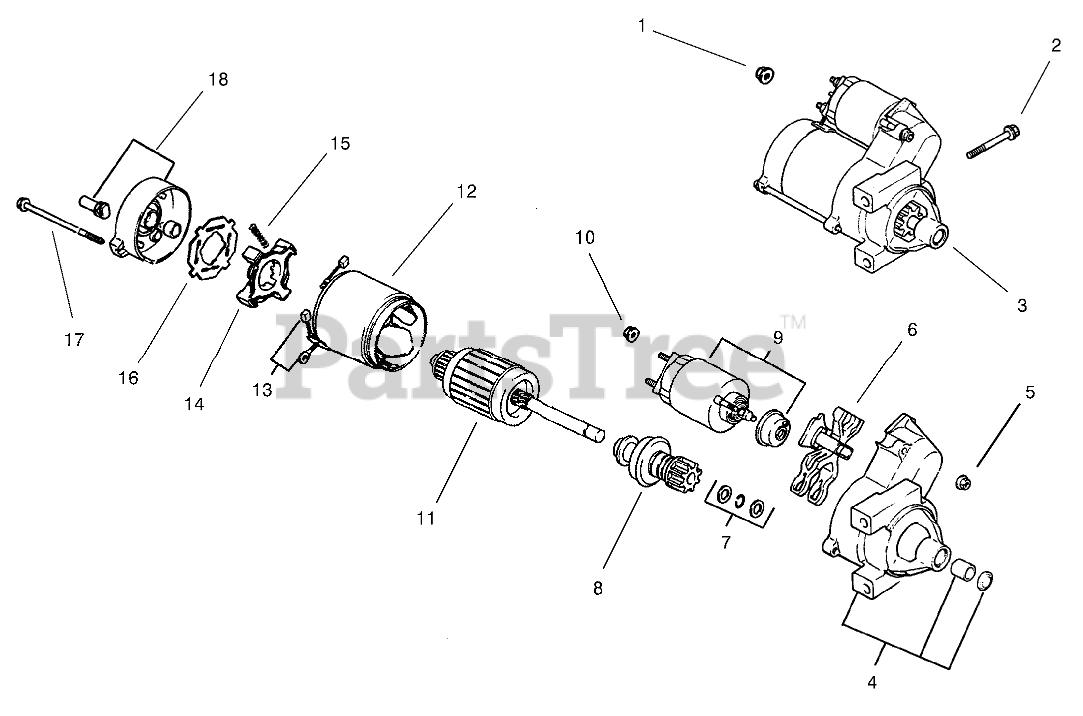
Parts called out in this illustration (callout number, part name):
1	Nut
2	Scew
3	Starter, solenoid shift assembly (Incl. 4-18)
4	Cap-Drive End
5	Nut
6	Lever Starter Drive
7	Washer
8	Drive Pinion
9	Solenoid
10	Nut
11	Armature-Starter
12	Frame
13	Kit, brush & spring (Includes 15)
14	Holder-Brush
15	Spring Brush
16	Insulator
17	Bolt
18	Commutator-End Cap
